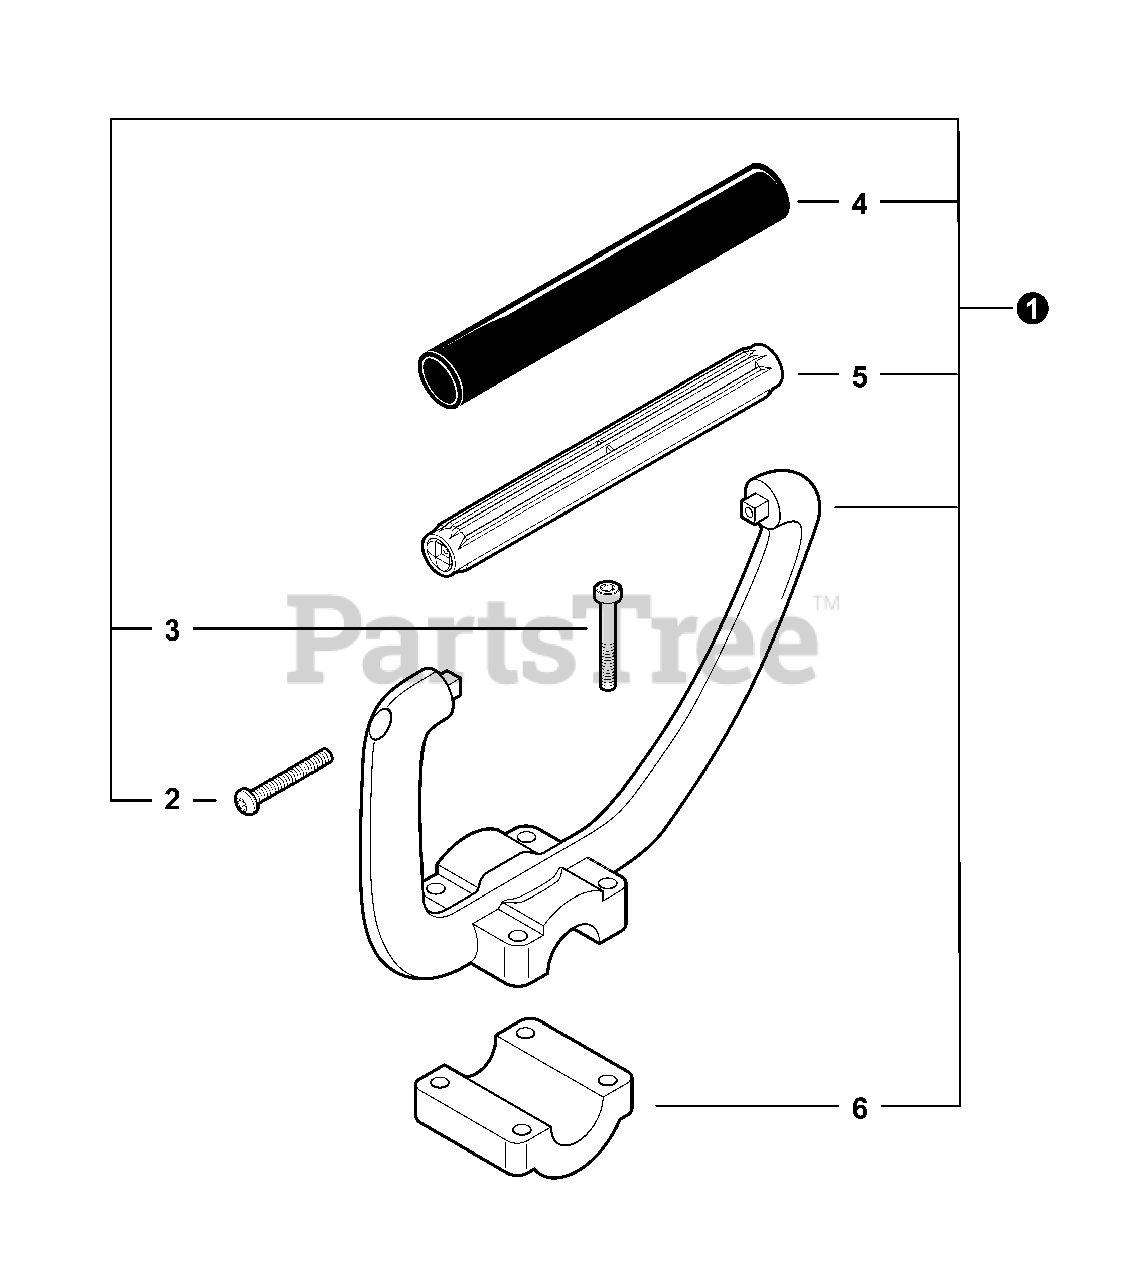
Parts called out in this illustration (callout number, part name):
1	LOOP HANDLE ASY
2	SCREW - 5×30 -- TAPPING
3	SCREW - 5×35
4	GRIP, HANDLE
6	BRACKET, HANDLE - LOWER
